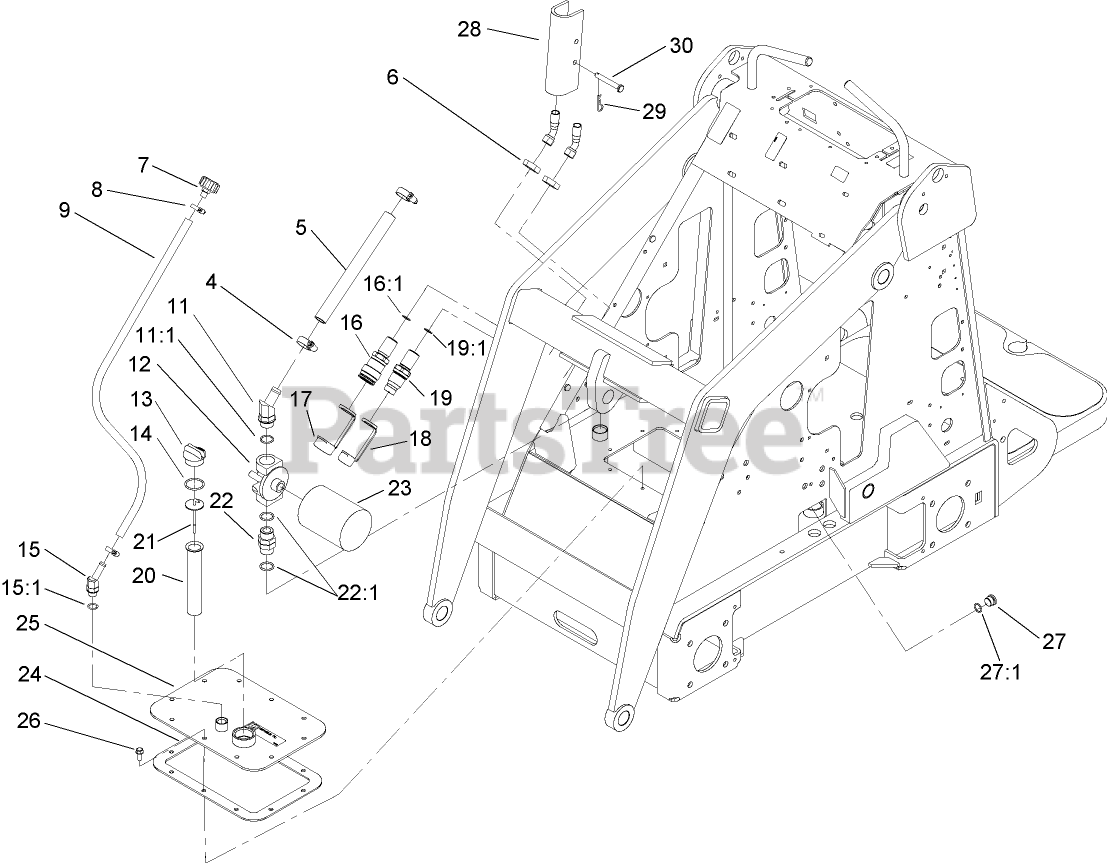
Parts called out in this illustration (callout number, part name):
4	CLAMP-HOSE
5	HOSE-HYD, SUCTION, HI
6	NUT-LOCK, BULKHEAD
7	BREATHER
8	CLAMP-HOSE
9	HOSE-VENT
11	ELBOW-45 DEG
11:1	O-RING
12	HEAD-FILTER
13	PLUG-PLASTIC
14	O-RING
15	FITTING-HYD, 45 DEG
15:1	O-RING
16	BULKHEAD COUPLER ASM
16:1	O-RING
17	CAP-DUST, COUPLER
18	CAP-DUST, NIPPLE
19	BULKHEAD NIPPLE ASM
19:1	O-RING
20	FILTER-SCREEN
21	DIPSTICK-OIL
22	FITTING-THREAD, STRAIGHT
22:1	O-RING
23	FILTER-OIL, TRANSMISSION
24	GASKET-COVER
26	SCREW
27	PLUG-HEX
27:1	O-RING
28	LOCK-CYLINDER
29	PIN-HAIR
30	PIN-CLEVIS
